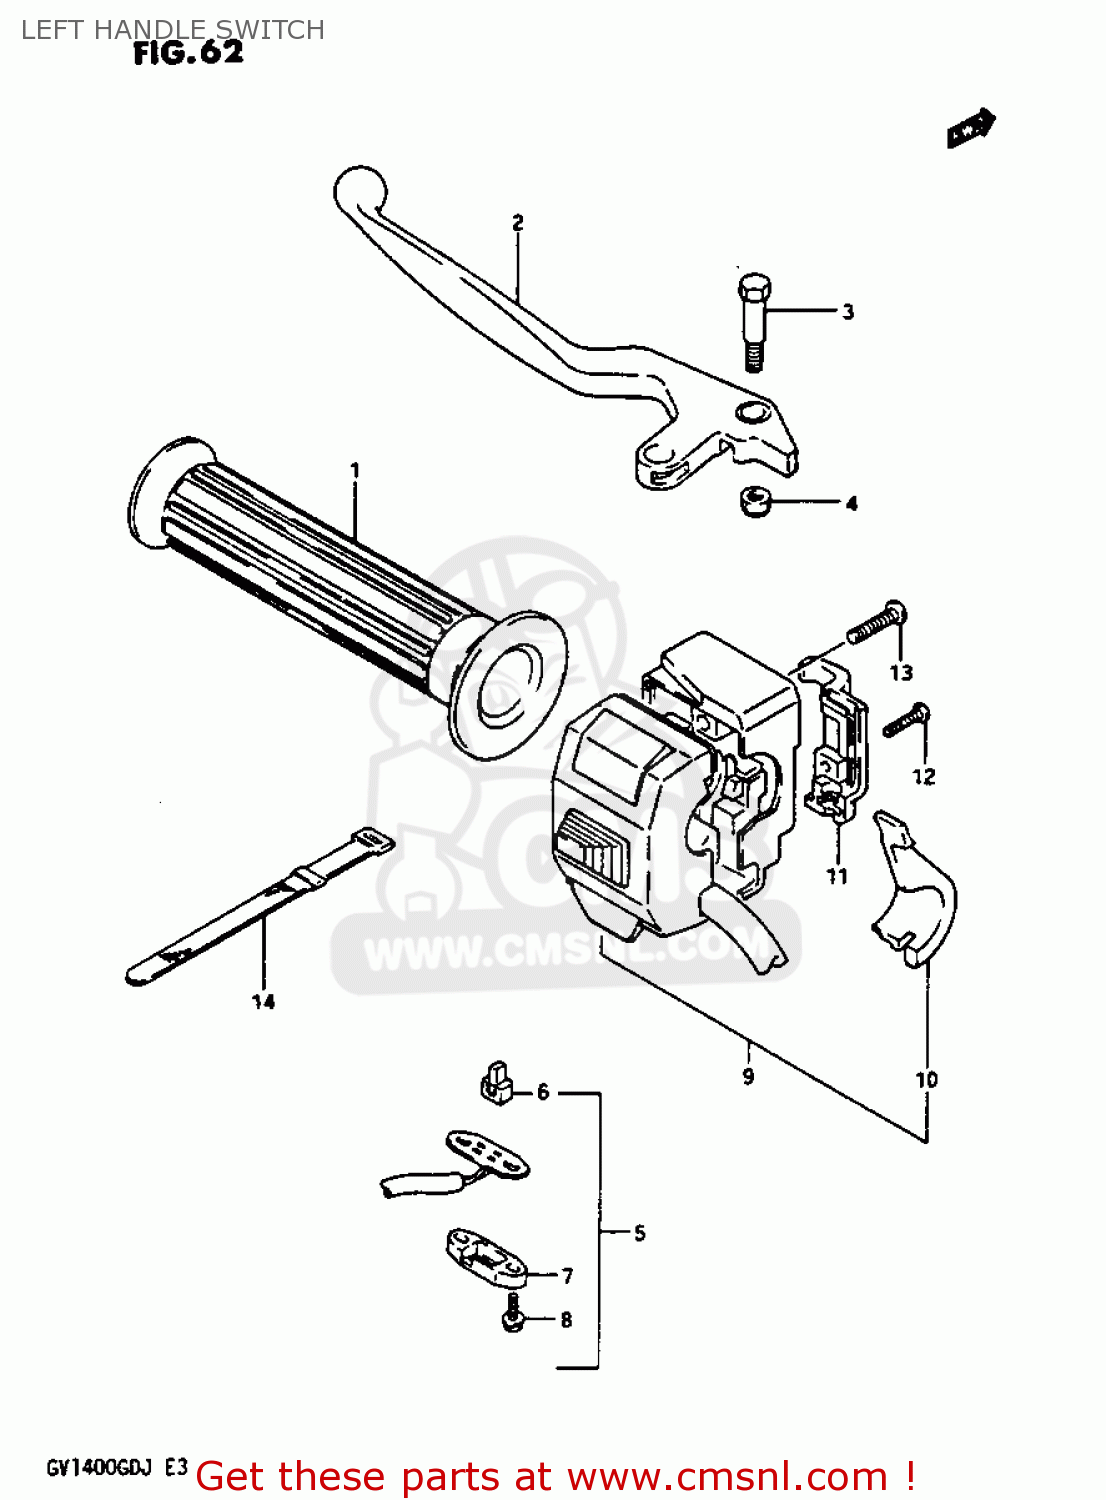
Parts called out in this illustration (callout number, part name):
1	GRIP,LEFT
2	LEVER,CLUTCH
3	BOLT,LEVER
4	NUT
5	SWITCH ASSY,CLUTCH
6	CONTACT,SWITCH
7	COVER,FR BK TERMINAL BASE
8	SCREW
9	SWITCH ASSY,HANDLE LH
10	LEVER,CHOKE
11	COVER
12	SCREW
13	SCREW 5X20
14	CLAMP(L:187)
